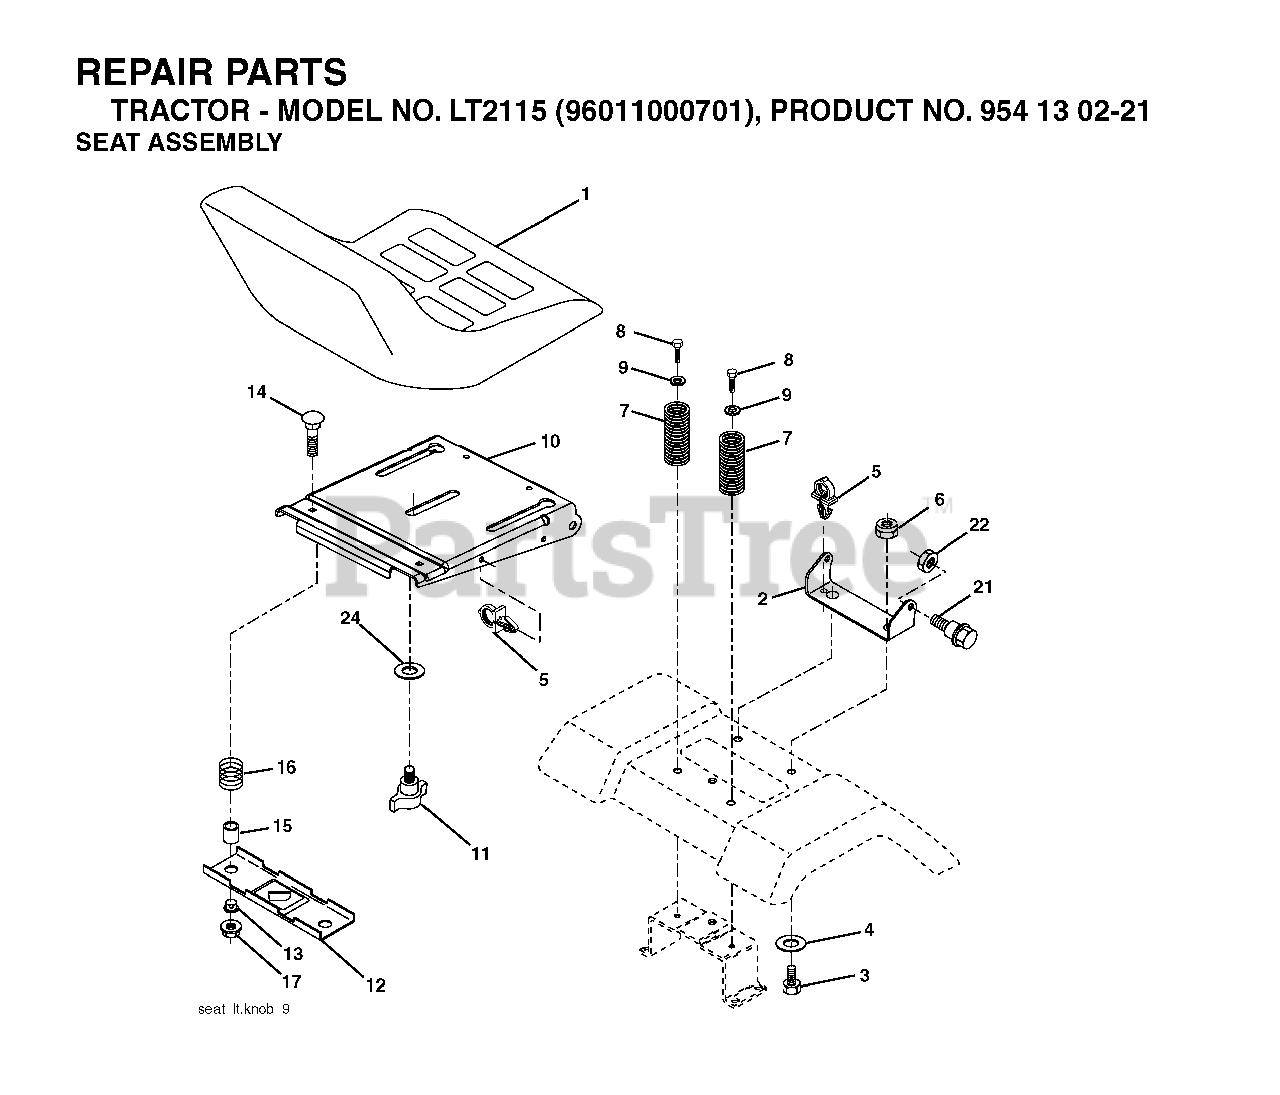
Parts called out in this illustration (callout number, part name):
2	BRKT.PIVOT.FENDER
4	WASHER PM
5	PUSH CLIP
6	NUT
7	SPRING COMPRESSION
8	SCREW 3/8-16X1
9	WASHER
11	KNOB.SEAT.ADJ.WINGNUT
12	BRKT SWITCH
14	BOLT.ROUND.HEAD.SQUARE.NECK
15	SPACER SPLIT 28X.96
17	NUT T
21	BOLT.SHOULDER.5/16-18
22	NUT.71038.31-18.HEX.NYLOCK
